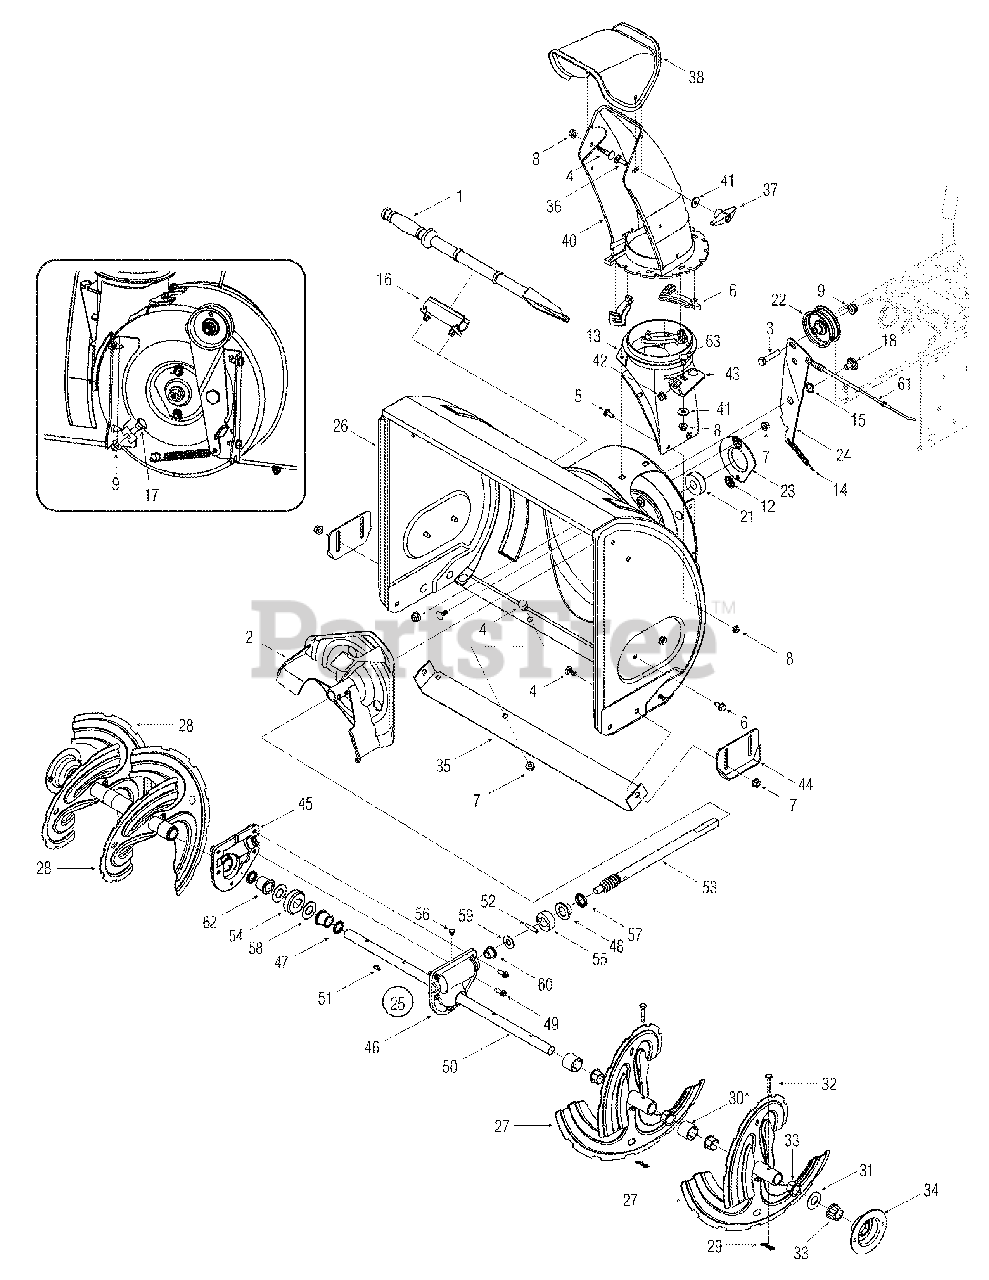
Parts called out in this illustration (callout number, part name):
1	Clean Out Tool
3	Hex Screw, 3/8-16, 1.75, Gr5, Std
4	Bolt, Carriage, 5/16-18, .750 Gr1
5	Screw, Carriage, 1/4-20, .75, Gr5
6	Screw, Self-tapping, 5/16-12, 0.750
6	Chute, Keeper Flange
7	Nut, Flange Lock, 5/16-18, Grf, Nylon
8	Nut, Flange Lock, 1/4-20, Grf, Nylon
9	Nut, Flange Lock, 3/8-16, Grf, Nylon
10	Internal Cotter Pin
11	Cable, Tie, 3/16 x .05 x 7.4
12	Nut, Push-on, .25 Diameter
13	Chute, Adapter 5" Diameter
14	Spring, Extension, .38 OD x 3.6
15	Washer, Wave, .625 x.885 x.015
16	Mount, Clean Out Tool
17	Screw, Shoulder, .498 x .340, 3/8-16
18	Screw, Shoulder, .625 x .170, 3/8-16
19	Pin, Shear, .25 x 1.50, Gr2
20	Bearing, Hex Flange x .75 ID
21	Bearing, Ball, .75 ID x 1.85 OD
22	Idler Pulley, Flat 2.75 OD
23	Housing, Bearing, 1.85 ID
25	Gearbox Assembly, Auger, 22"
25	Gearbox Assembly, Auger, 24"
25	Gearbox Assembly, Auger, 26"
25	Gearbox Assembly, Auger, 28"
25	Gearbox Assembly, Auger, 30"
29	Cotter Pin, Bow-Tie
30	Spacer, 1.25 OD x .75 ID x 1.00
31	Washer, Flat, .76 x 1.49 x .06
32	Shear Pin, .25 x 1.50, Gr2
33	Bushing, Flange, .800 ID x .910 OD
33	Bushing, Flange, X .75 ID
36	Bolt, Carriage, 5/16-18, 1.0
37	Knob Assembly
38	Chute, Upper, w/ Domestic Label
39	Chute, Keeper Flange
40	Chute, Lower, 5.0 Diameter
41	Washer.349 ID x .879 OD x .063
42	Bushing, Plastic, .380
45	Housing, Auger, RH Reduced
46	Housing, Auger, LH Reduced
47	Seal, Oil, .750 ID
48	Bearing, Flange, .75 ID x 1.00 OD x .59
49	Screw, Self-tapping, 1/4-20, 0.750
50	Axle, Auger, 22"
50	Axle, Auger, 24"
50	Axle, Auger, 26"
50	Axle, Auger, 28"
50	Axle, Auger, 30"
51	Key, Hi-pro 3/16 x 5/8
52	Pin, Dowel, .25 OD x 1.2
53	Shaft, Worm .75 OD
54	Gear, Worm 20T
55	Collar, Thrust
56	Plug, 1/4 x .437
57	Seal, Oil, .75 x 1 x .131
58	Washer, Flat, .760 ID x 1.5 OD
59	Washer, Flat, .51 x 1.12
60	Bearing, Flange, .75 ID x 1.00 OD x .925
61	Auger Clutch Cable, 44.75"
62	Bearing, Flange, .75 ID x 1.00 OD x .975
63	Bolt, Carriage, 5/16-18, 1.0 Gr1
